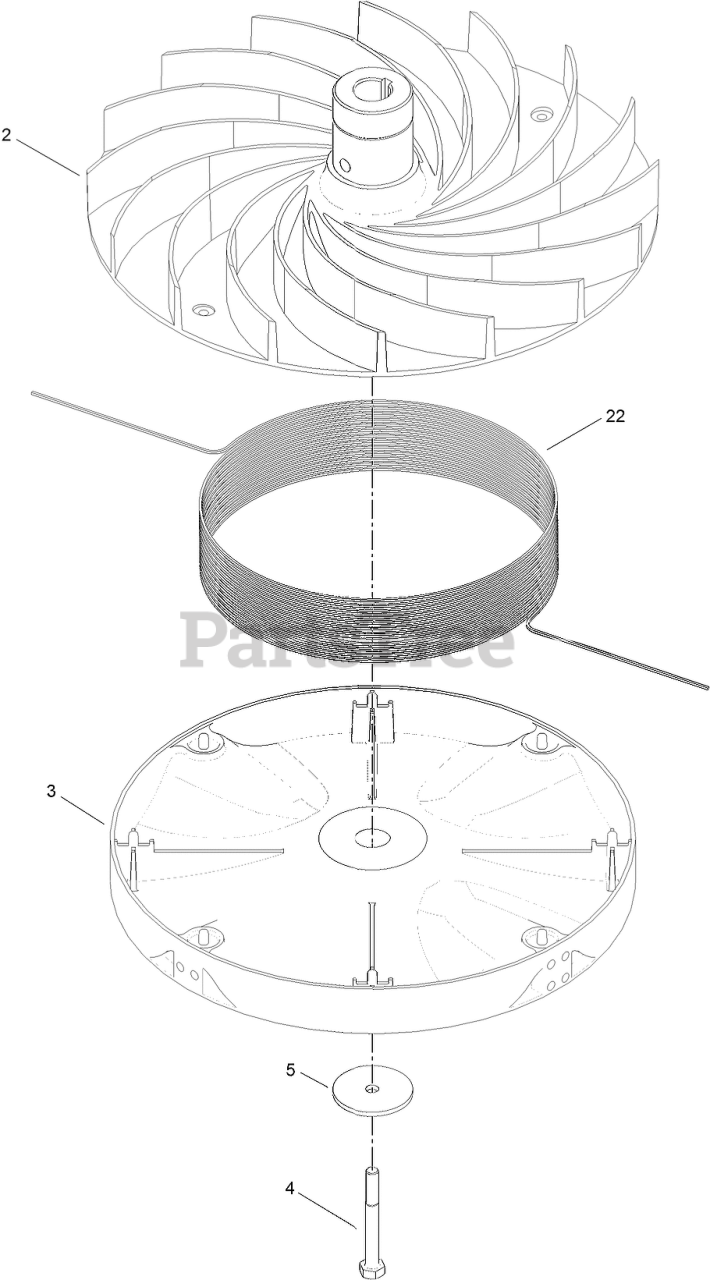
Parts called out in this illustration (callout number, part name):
2	IMPELLER
3	DISC-CUTTING
4	BOLT-HH
5	DISC-SPRING
22	LINE-CUTTING, NYLON (27M SPOOL)
